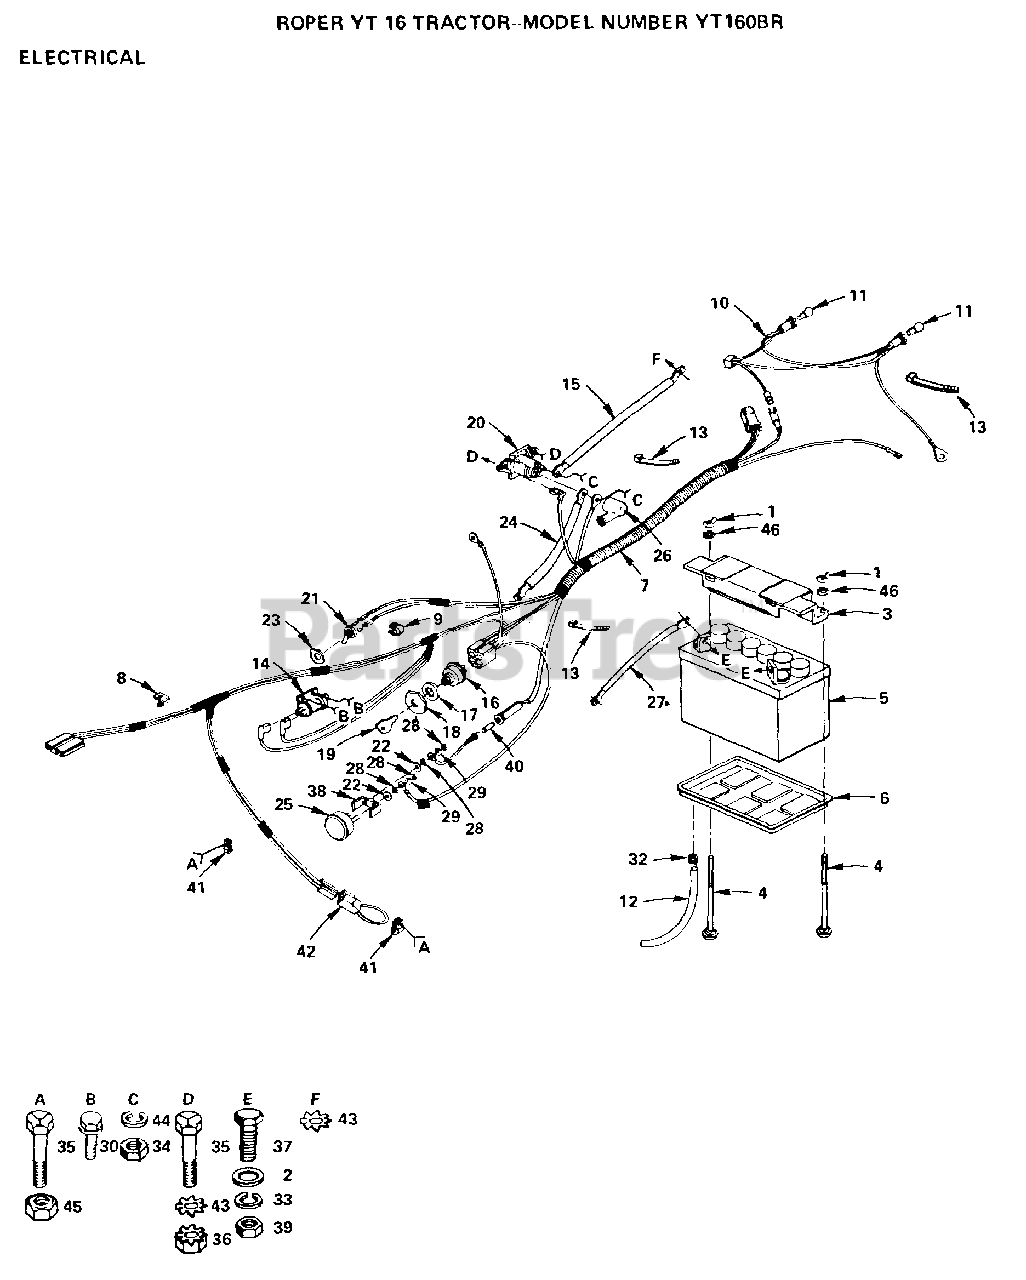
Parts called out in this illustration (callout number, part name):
2	WASHER
4	BOLT
6	"TRAY T, BATTERY"
8	CLIP GTV
10	HARNESS T
11	HEADLAMP BULB
13	WIRE TIE
17	LOCKWASHER
18	CONDUIT NUT L
21	LIGHT SWITCH T
24	CABLE-BATTERY T
25	AMMETER T
27	CABLE T
33	LOCKWASHER
34	NUT
35	BOLT
36	NUT
37	BOLT LT
40	FUSE-30 AMP
41	CLIPT
46	LOCKWASHER GT
